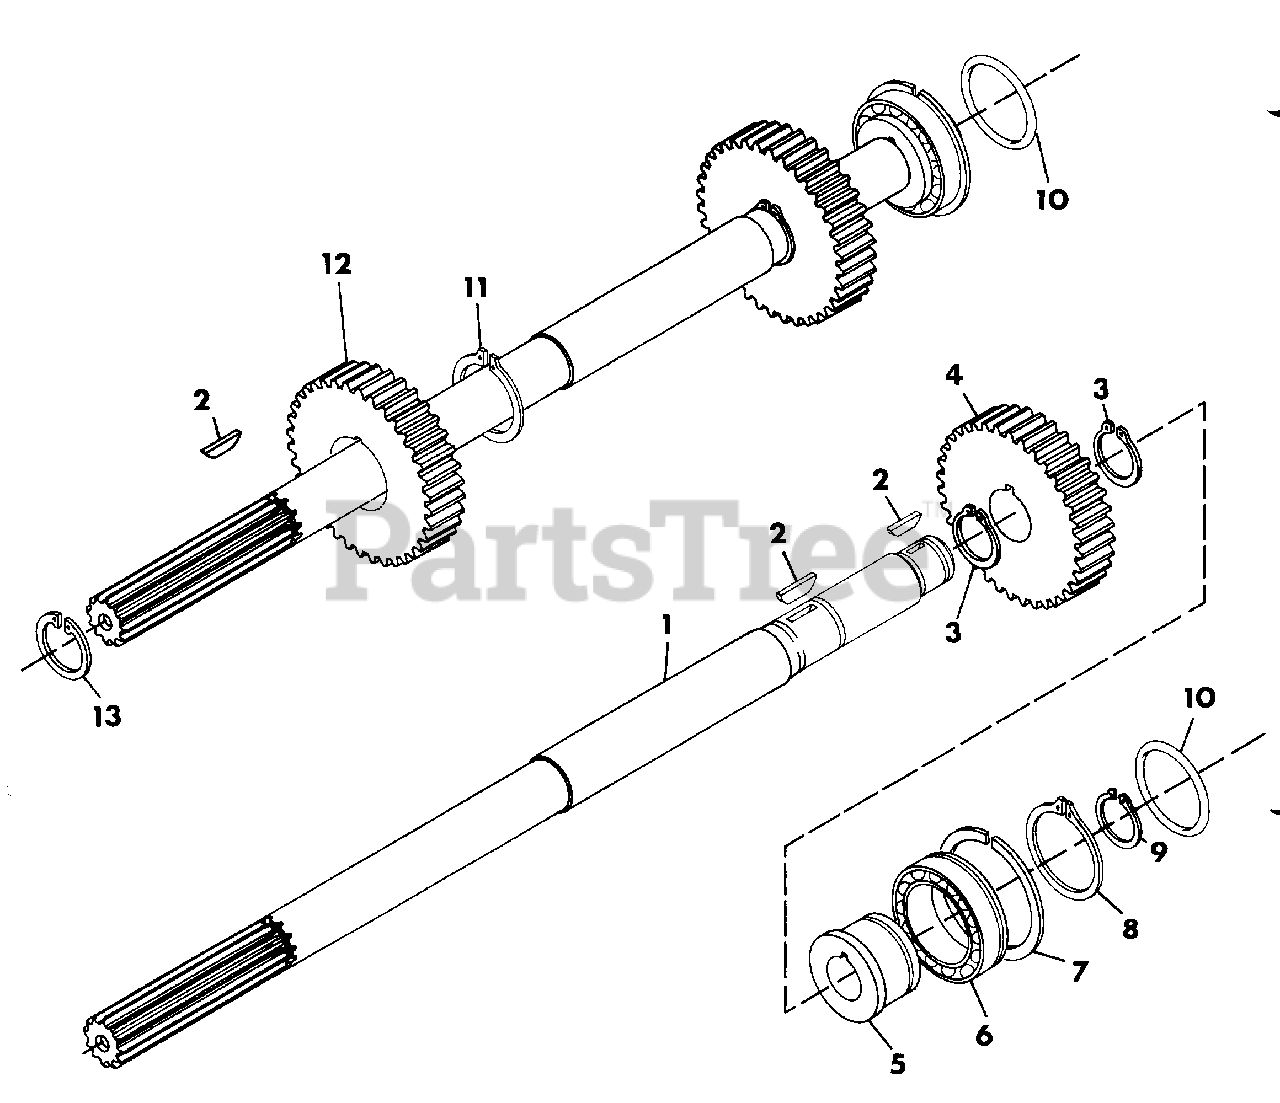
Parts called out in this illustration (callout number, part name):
1	SHAFT, PTO CROSS
2	KEY, WOODRUFF .187X.750 HARD #9
3	RING, RETAINING .984 SHAFT
4	GEAR, PTO CROSS SHAFT
5	ADAPTER, PTO BEARING
6	BEARING, BALL 1.378X2.440X.551
7	RING, RETAINING
8	RING, RETAINING
9	RING, RETAINING .750 SHAFT
10	O-RING, 2.50X2.750X.125
11	RING, RETAINING 1.562 SHAFT
12	GEAR, PTO
13	RING, RETAINING
